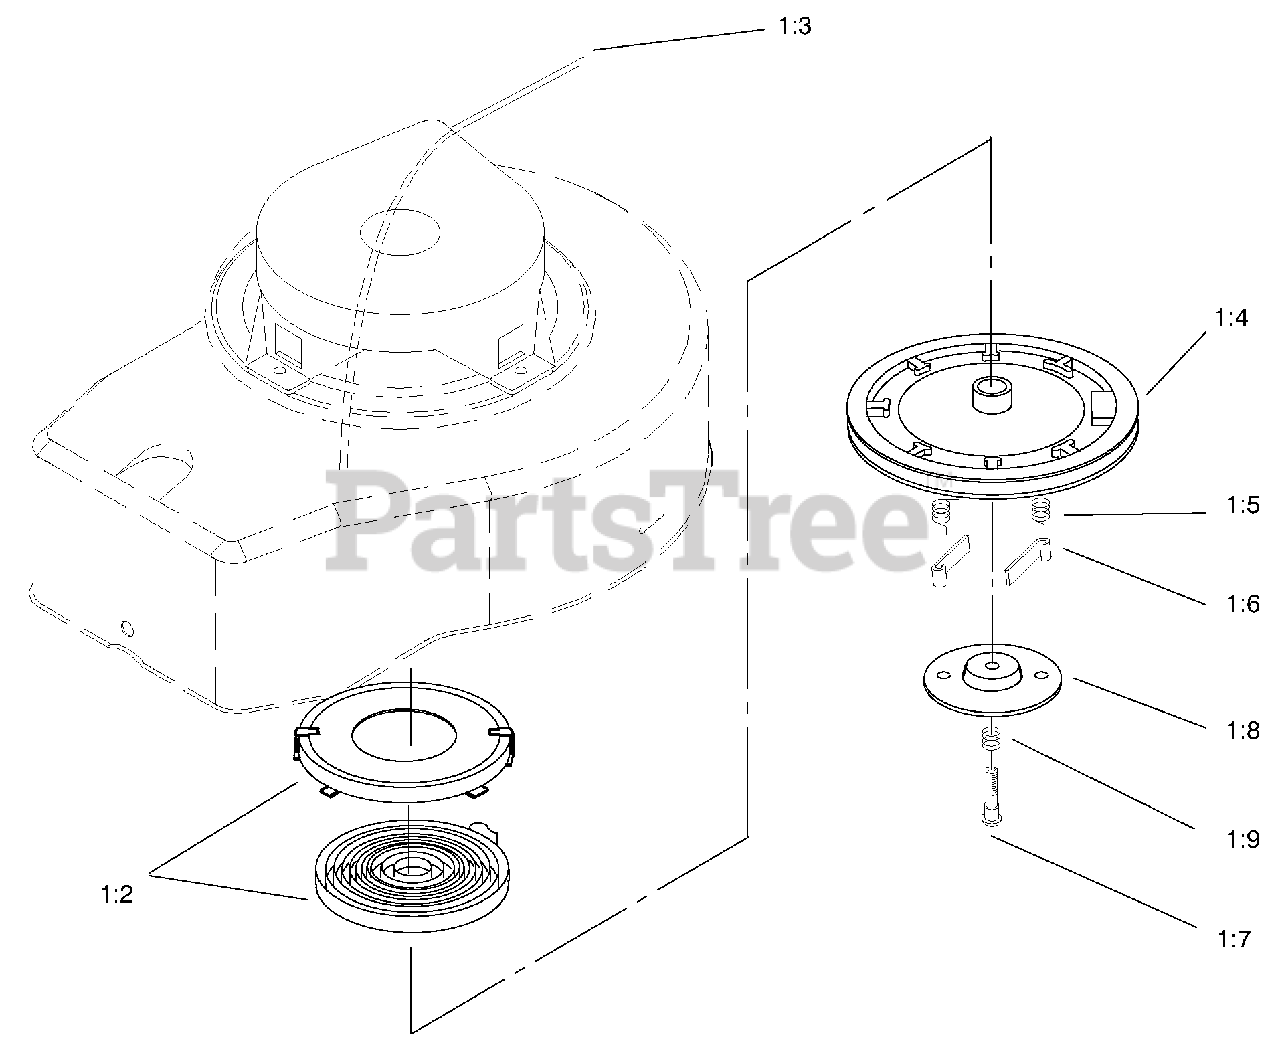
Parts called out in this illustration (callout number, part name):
1:2	Keeper ASM
1:3	88 5/8 Grey Rope
1:4	Pulley ASM
1:5	Spring-Dog
1:7	Spring-Brake
1:8	Retainer
1:9	Screw-Center
